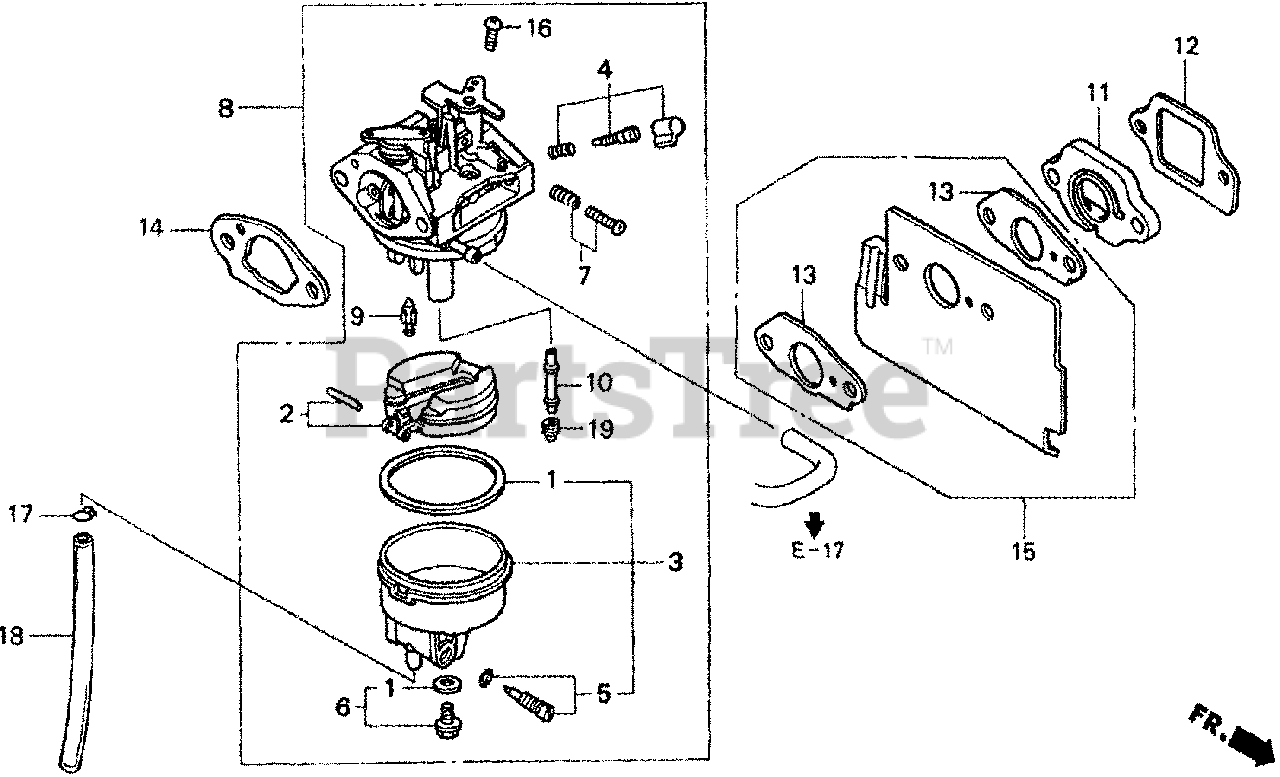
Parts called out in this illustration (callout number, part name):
1	GASKET SET
3	CHAMBER SET, FLOAT
5	SCREW SET, DRAIN
6	SCREW SET B
8	CARBURETOR ASSY. (BB61B C)
8	CARBURETOR ASSY. (BB61B D)
9	VALVE, FLOAT
10	NOZZLE, MAIN
11	INSULATOR, CARBURETOR
12	GASKET, INSULATOR
13	GASKET, CARBURETOR
14	GASKET, CARBURETOR (CHOKE SIDE)
15	GUIDE, AIR
16	SCREW, PAN (5X6)
17	CLIP, TUBE (B6.5)
18	BULK HOSE, VINYL (4X7X8000) (4X7X150)
19	JET, MAIN (#60)
19	JET, MAIN (#62)
19	JET, MAIN (#65)
